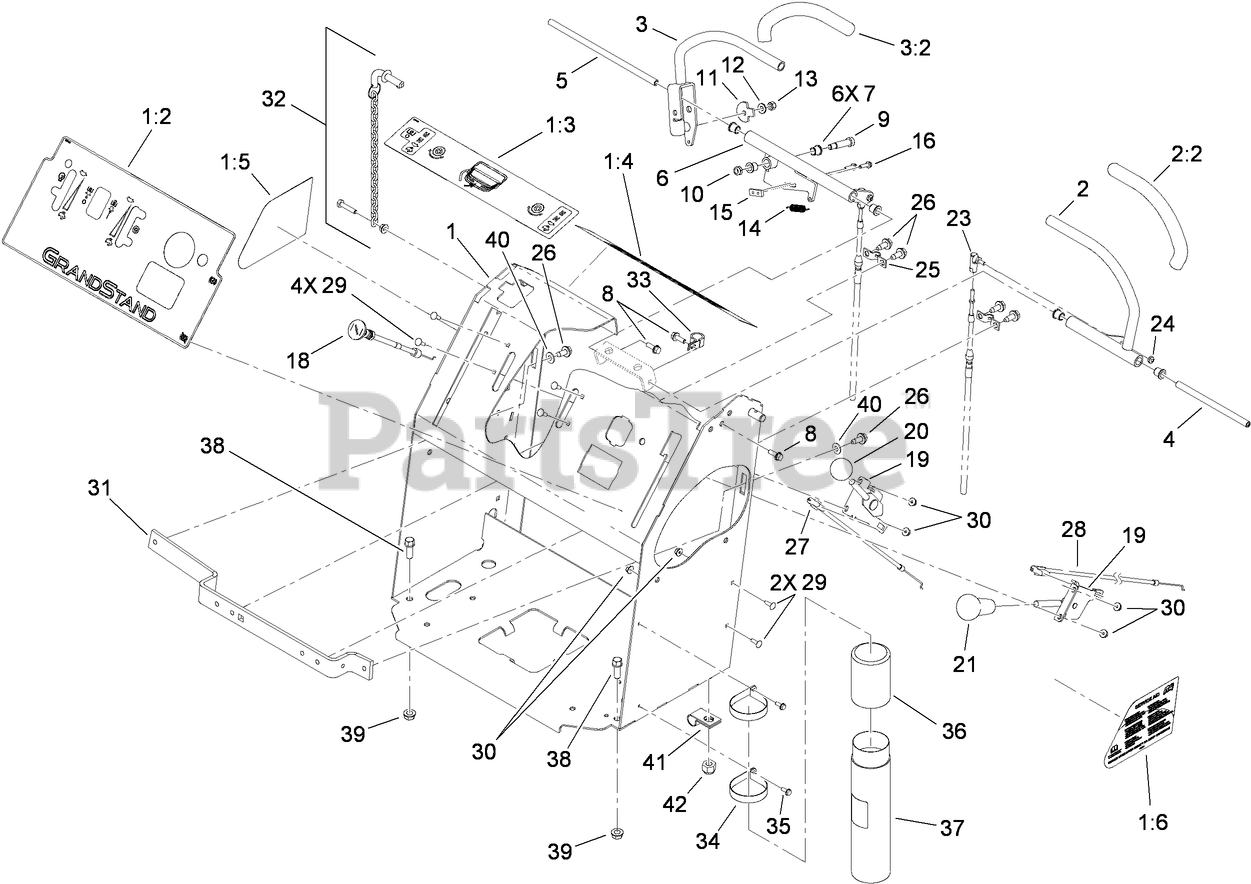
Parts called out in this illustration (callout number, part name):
1	CONTROL TOWER ASM
1:2	DECAL-PANEL, CONTROL
1:3	DECAL-OPC
1:4	DECAL-WARNING
1:5	DECAL-HOC
1:6	DECAL-AID, SERVICE
2	LH LEVER ASM
2:2	GRIP-LEVER
3	RH LEVER ASM
3:2	GRIP-LEVER
4	SHAFT-PIVOT
5	SHAFT-PIVOT, MOTION CONTROL
6	MOTION CONTROL ASM
7	BEARING
8	SCREW-HHF
9	SCREW-HSH
10	NUT-LOCK, NI
11	CAM-LEVER
12	WASHER-FLAT
13	NUT-LOCK, NI
14	SPRING-EXTENSION
15	PLATE-TAPPED
16	SCREW-HWH
18	Control-Choke, Push / Pull
19	LEVER-CONTROL
20	KNOB-BALL
21	KNOB-GRIP, SOFT
23	JOINT-BALL
24	NUT-LOCK, NI
25	CLAMP-CABLE
26	SCREW-HWHTF
27	CABLE-CONTROL
28	CABLE-SPEED
29	BOLT-CARR
30	NUT-HF
31	BAR-CABLE
32	HOC PIN ASM
33	CLAMP-CABLE
34	CLAMP-R
35	SCREW-TAPTITE
36	CAP-HOUSING
37	TUBE-MANUAL
38	SCREW-HWH
39	NUT-HHF, WHIZ
40	WASHER-PLAIN
41	R-CLAMP
42	NUT-LOCK, NI
